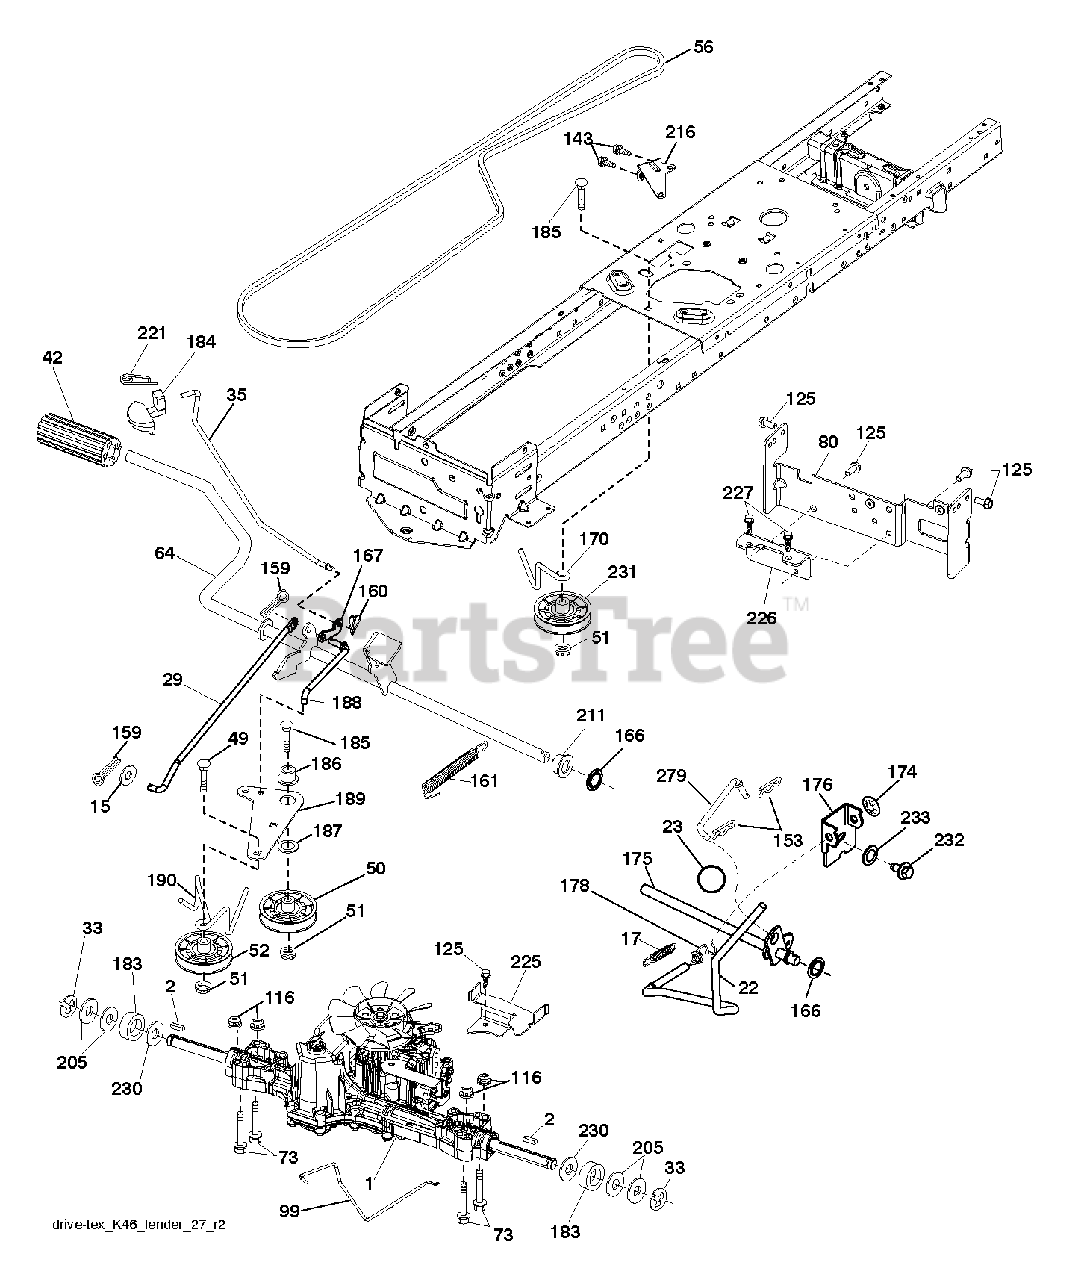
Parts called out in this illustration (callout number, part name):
1	Husqvarna TBD
2	SQUARE KEY
15	WASHER
17	SPRING.BRAKE.K46.GREEN
23	KNOB.DUCKHEAD.1/2
29	ROD.BRAKE.K46
35	ROD.CNTRL.PARK.PREDATOR.LT.TEX
42	PEDAL COVER T
50	IDLER.FLAT.910.OFFSET
51	NUT LOCK FLG 3/8-16 UNC
52	IDLER.V-GROOVE.910.OFFSET
56	V-BELT.MOWER.92.40.42/K46
64	SHAFT.ASM.PEDAL.BRAKE.
73	BOLT HEX 5/16-18 GR 5
80	STRAP.TORQUE.K46.K57R.TT
99	ROD.SPRING.BYPASS.K46.LT.Z
116	NUT LOCK HEX FLANGE 5/16-18
125	SCREW
143	SCREW LT
153	RETAINER M
159	COTTER PIN
160	RETAINER CLIP
161	SPRING, RETURN LT
166	NUT.PUSH.625
167	LATCH.BRAKE.SPRING
170	KEEPER.CENTER SPAN.1.688
174	NUT.PUSH.500.2006
175	SHAFT.ASM.SHFT.T2.TLT
176	ARM.CLEVIS.ROD.SHIFT
178	SPRING.SHIFT.GT2006
183	SPACER AXLE
184	HANDLE.PARKING.BRK.PRED.LT.RED
186	SPACER.RETAINER
187	WASHER 12/32X2X10GA
188	RP LINK.CLUTCH.GROUND.DRIVE
189	BELLCRANK.GROUND.DRIVE.TEX.
190	KEEPER.BELLCRANK.DRIVE
211	BUSHING.SHAFT.BRAKE.HAND
216	BRACKET.PULLEY.IDLER.W/TEX
221	RETAINER.SPRING.CLIP.H
225	KEEPER.BELT.TRANSAXLE.K46
226	BRACKET.MOUNT.TORQUE.K46.TLT
227	SCREW
230	WASHER.HARDENED
231	IDLER.V-GROOVE.1.688.OFFSET
232	BOLT FIN HEX 7/16-14 X 1
233	WASHER SERRATED
279	LINK.SHIFT.
